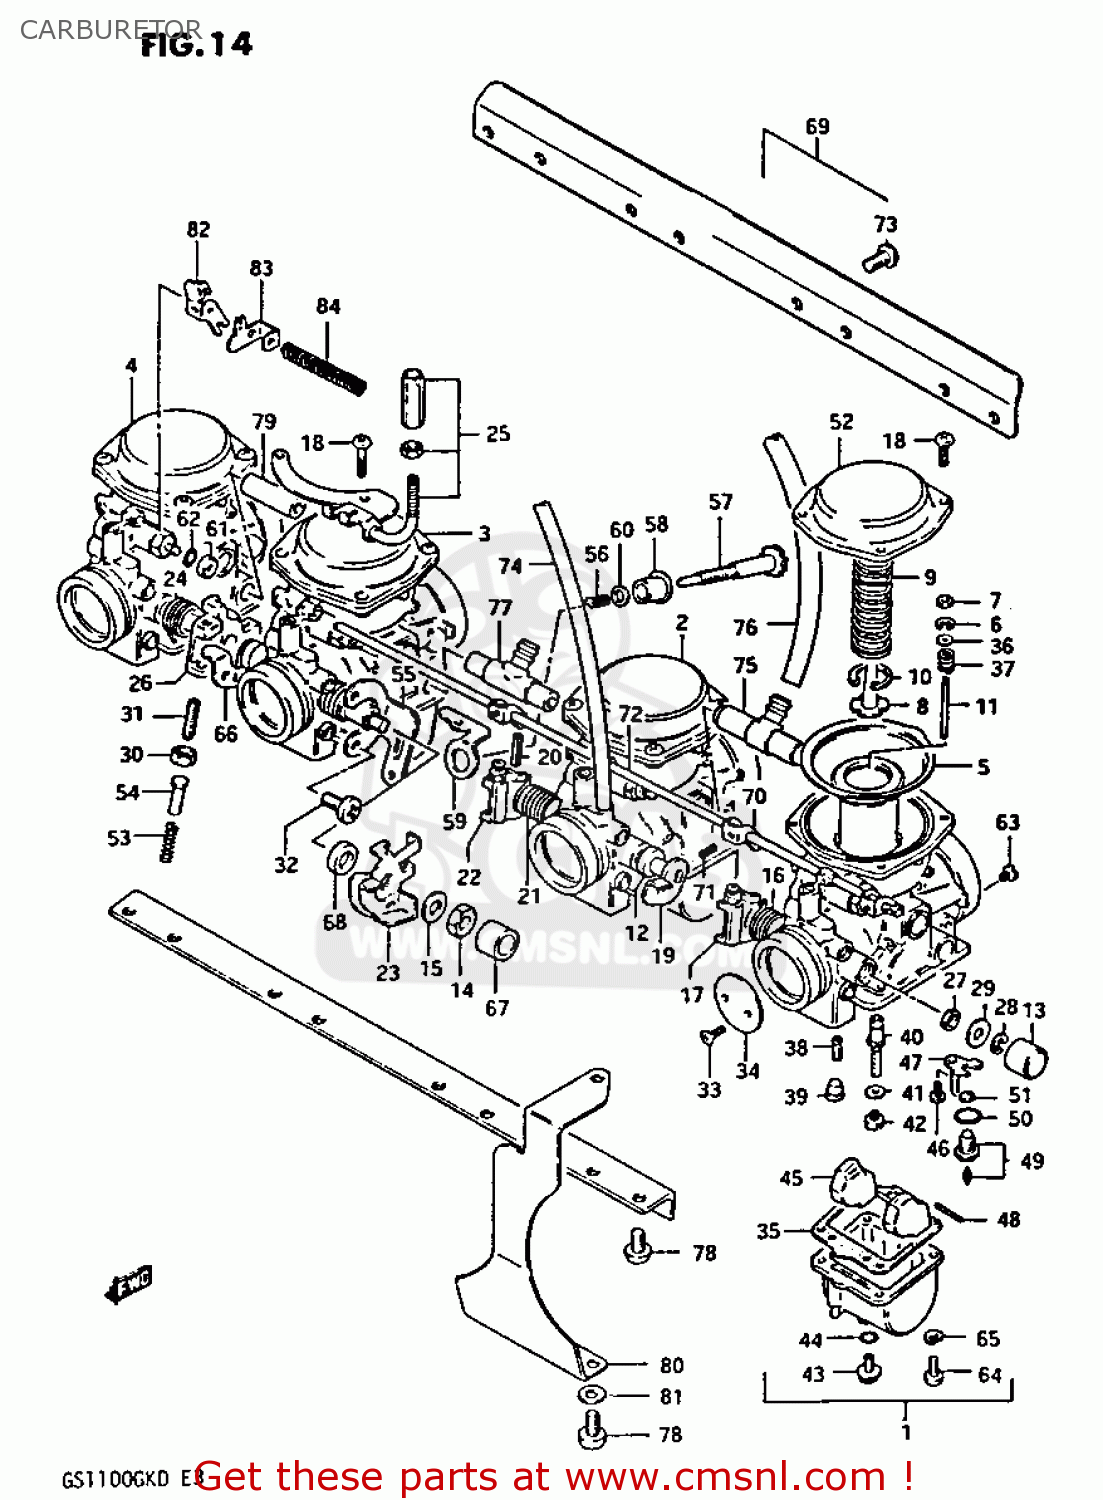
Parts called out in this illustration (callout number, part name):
1	CARBURETOR ASSEMBLY
2	CARBURETOR ASSEMBLY
3	CARBURETOR ASSEMBLY
4	CARBURETOR ASSEMBLY
5	DIAPHRAGM ASSY
6	CLIP,NEEDLE
7	RING
8	HOLDER,GUIDE
9	SPRING
10	E RING
11	NEEDLE,JET
12	GASKET
13	CAP
14	NUT
15	WASHER
16	SPRING,THROTTLE SHAFT
17	SHAFT,THROTTLE
18	SCREW
19	SHAFT,THROTTLE
20	PIN,THROTTLE SHAFT
21	SPRING,THROTTLE SHAFT
22	LEVER,THROTTLE SHAFT
23	LEVER ASSEMBLY,THROTTLE
24	SPRING,THROTTLE SHAFT
25	BRACKET,THROTTLE CABLE
26	SHAFT,THROTTLE
27	SEAL
28	E RING
29	GASKET,THROTTLE SHAFT (NAS)
30	NUT
31	SCREW
32	SCREW
33	SCREW
34	VALVE,THROTTLE
35	GASKET,FLOAT CHAMBER (NAS)
36	WASHER
37	SPRING
38	JET,PILOT
39	PLUG,NEEDLE JET
40	JET,NEEDLE
41	WASHER,NEEDLE NOZZLE
42	JET,MAIN(115)
43	PLUG,DRAIN
44	GASKET (NAS)
45	FLOAT
46	SCREW 4X6
47	PLATE,NEEDLE VALVE FITING
48	PIN,FLOAT
49	VALVE ASSY,NEEDLE
50	O-RING,NEEDLE VALVE
51	FILTER
52	COVER,DIAPHRAGM
53	SPRING,THROTTLE SCREW
54	PIN,THROTTLE LEVER
55	BRACKET,THROTTLE ADJUST
56	SPRING
57	SCREW
58	BUSH
59	BRACKET,THROTTLE ADJUST
60	WASHER
61	CAP,STARTER VALVE
62	O RING
63	JET,AIR
64	SCREW
65	LOCK WASHER
66	SHAFT,THROTTLE
67	RING
68	RING
69	CARBURETOR ASSEMBLY
70	LEVER
71	SCREW
72	SHAFT,STARTER
73	SCREW
74	HOSE
75	NIPPLE
76	HOSE,CARBURETOR
77	NIPPLE
78	SCREW
79	NIPPLE
80	CLAMP
81	WASHER
82	PLATE,CHOKE CABLE
83	LEVER,CHOKE CABLE
84	SPRING,CHOKE CABLE
